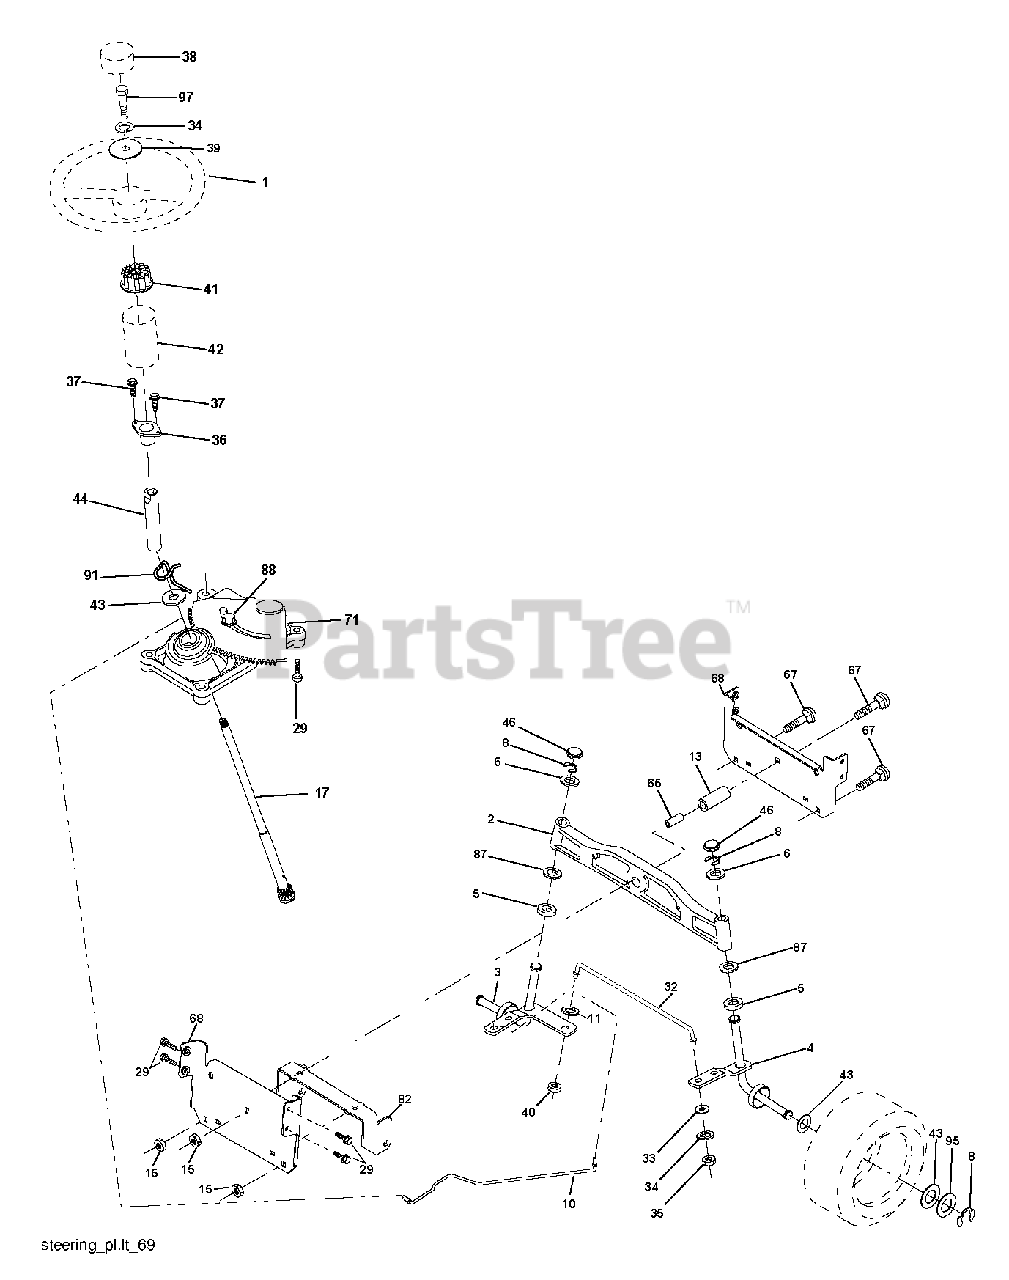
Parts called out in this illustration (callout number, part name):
1	WHEEL.STEERING.PREM.2.BLK
2	AXLE ASSY FRONT
3	SPINDLE.ASM.LH.15"TIRES
4	SPINDLE.ASM.RH.15"TIRES
8	RING CLIP
10	DRAGLINK.15".TIRES.2001
11	WASHER, LOCK 3/8
13	TUBE, PIVOT AXLE
15	NUT
17	SHAFT STEERING SPLINE
29	SCREW, 3/8-16X3/4
33	WASHER M
34	LOCKWASHER
35	NUT, CROWNLOCK
36	BUSHING, STEERING
38	INSERT.CAP.STRG.WH.BLACK
39	WASHER.11/32
40	NUT CROWNLOCK 3/8-24
41	ADAPTER, WHEEL STNG..
42	BOOT.STEERING.SHAFT.BLACK
44	SHAFT.EXTEN.STRG.SPLINE
46	CAP.SPINDLE
65	SPACER BRACE AXLE
67	BOLT CARRIAGE
68	BRACE.AXLE.15"TIRES
71	STEERING ASM
82	BRACKET.SUSP.CHASSIS.FRONT.15
87	WASHER, FLAT .781 X 1 1/2"
88	BOLT, SHOULDER 7/16-20
91	CLIP.STEERING
95	WASHER.HARDENED
